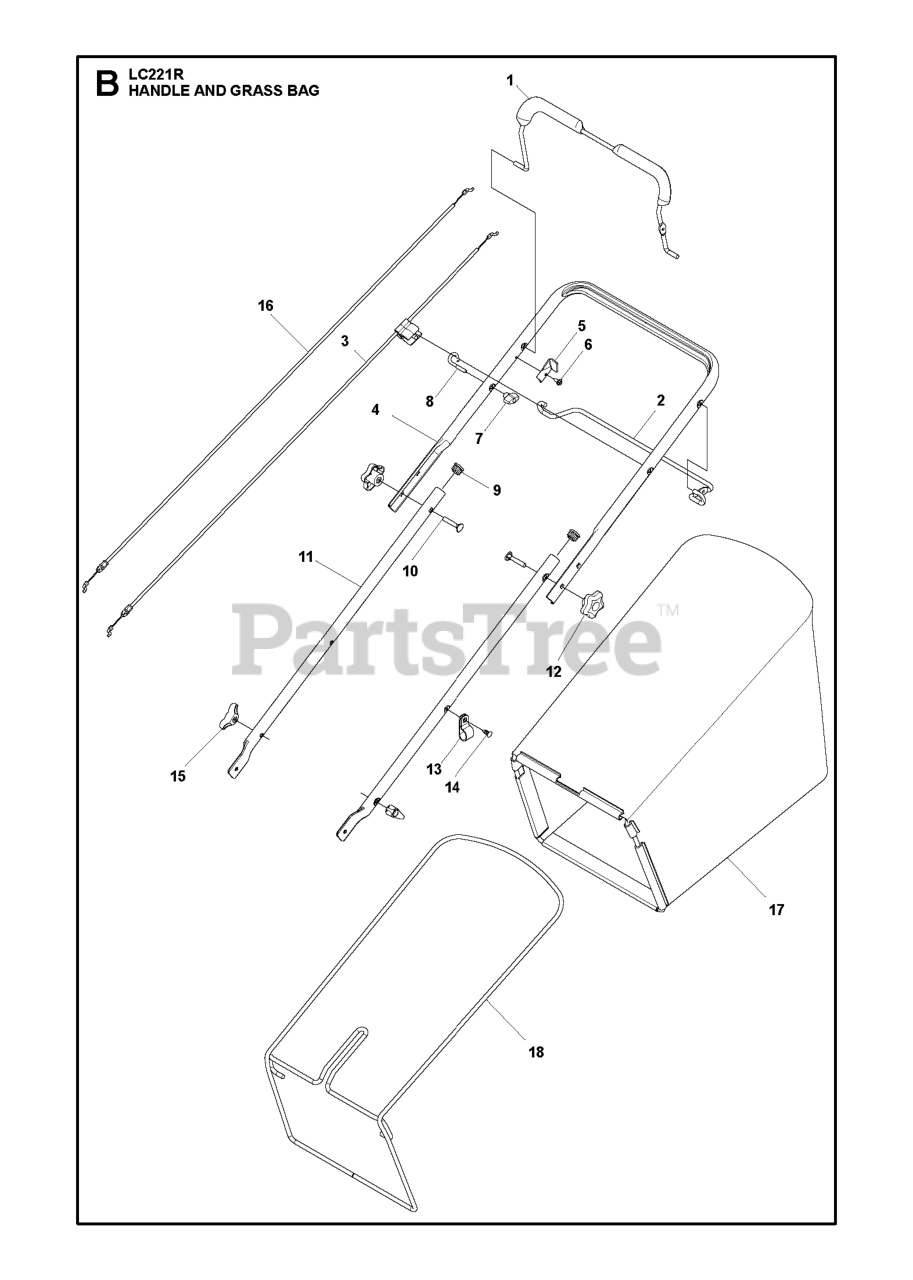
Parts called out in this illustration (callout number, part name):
1	BAIL.ARM.ASSY:STRAIGHT OM
2	BAIL.CONT.DR.S/S.ROUND.BLACK
3	CABLE.MZR.DUAL.5.95EXT45.92CON
4	HANDLE.UPP.DST.EXTCR.SM.SP.498
5	BRACKET.UPSTOP.RT
6	SCREW
7	T-KNOB.NEW ROPE GUIDE
8	GUIDE.ROPE.BLK.ZINC.CHROM
9	PLUG.PLASTIC.7/8".14-20.GAUGE
10	BOLT.CONCAVE.HEAD.RETAINING
11	HANDLE.LOW.2PC.2POS.21EFF.498
12	KNOB.HANDLE.PLASTIC.STAR.BLACK
13	CLIP.CABLE.BLK
14	FASTENER.PUSH.O.250X0.783
15	KNOB, DEFLECTOR
16	CABLE.DR.UB.NA.21EFF.RW
17	GBAG.C361029ER.HUSQ.GRY.21EFF
18	FRAME.GBAG.AWD.21.BLACK
